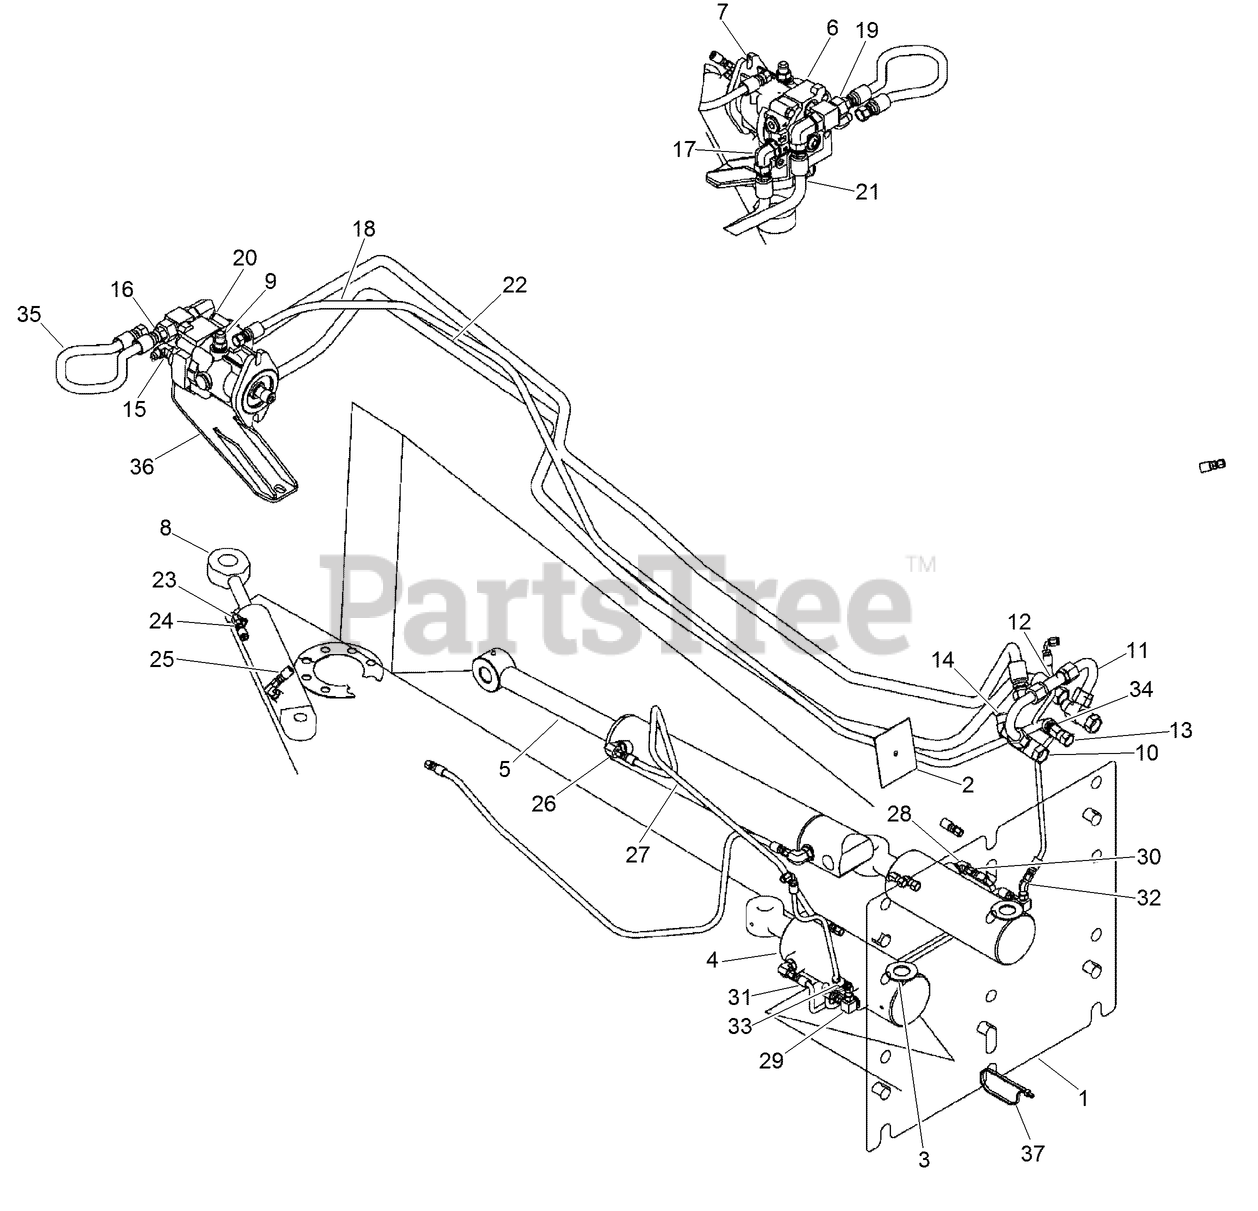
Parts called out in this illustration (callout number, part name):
1	PLOW - Basic, P95
2	SHIM-BUMPER
3	WASHER-FLAT
4	CYLINDER ASM-102 (4) ID x 152mm (6) stroke, plow swing
5	CYLINDER-PLOW LIFT
6	HYD MOTOR ASM
8	CYLINDER
9	CONNECTOR-Str Thd 5/8, 37FL-ORB 5/8
10	TEE-SWIVEL
11	TUBE ASM
12	VALVE-CHECK
13	ELBOW - 45 Swivel, 37FL 5/8 Tube
14	ELBOW-45 Deg 12MJ x 12FJ
15	ELBOW-90 Deg, 1/2 to 5/8
16	ADAPTER-Tee, ORB / JIC
17	ELBOW-90 Adj 37FL 3/4 Tube
18	ASSEMBLY - Hose
19	FITTING-Restrictor
20	ELBOW-SWIVEL, 90 DEG
21	ASSEMBLY - Hose
22	ASSEMBLY - Hose
23	ELBOW-90 DEG (ADJUSTABLE 37 DEG)
24	FITTING
25	ASSEMBLY - Hose
26	FITTING-ELBOW, 90 DEG
27	ASSEMBLY - Hose
28	ELBOW-90 Adj 37FL, 3/8 x 1/2 Tube
29	TEE-SPECIAL
30	ASSEMBLY - Hose
31	ASSEMBLY - Hose
32	FITTING-ELBOW, 45 DEG
33	HOSE ASSEMBLY - Hydraulic
34	ASSEMBLY - Hydraulic Hose
35	HOSE-Trencher Motor Flush
36	BRACKET - P95 Motor Mount
37	STRAP-TIE
